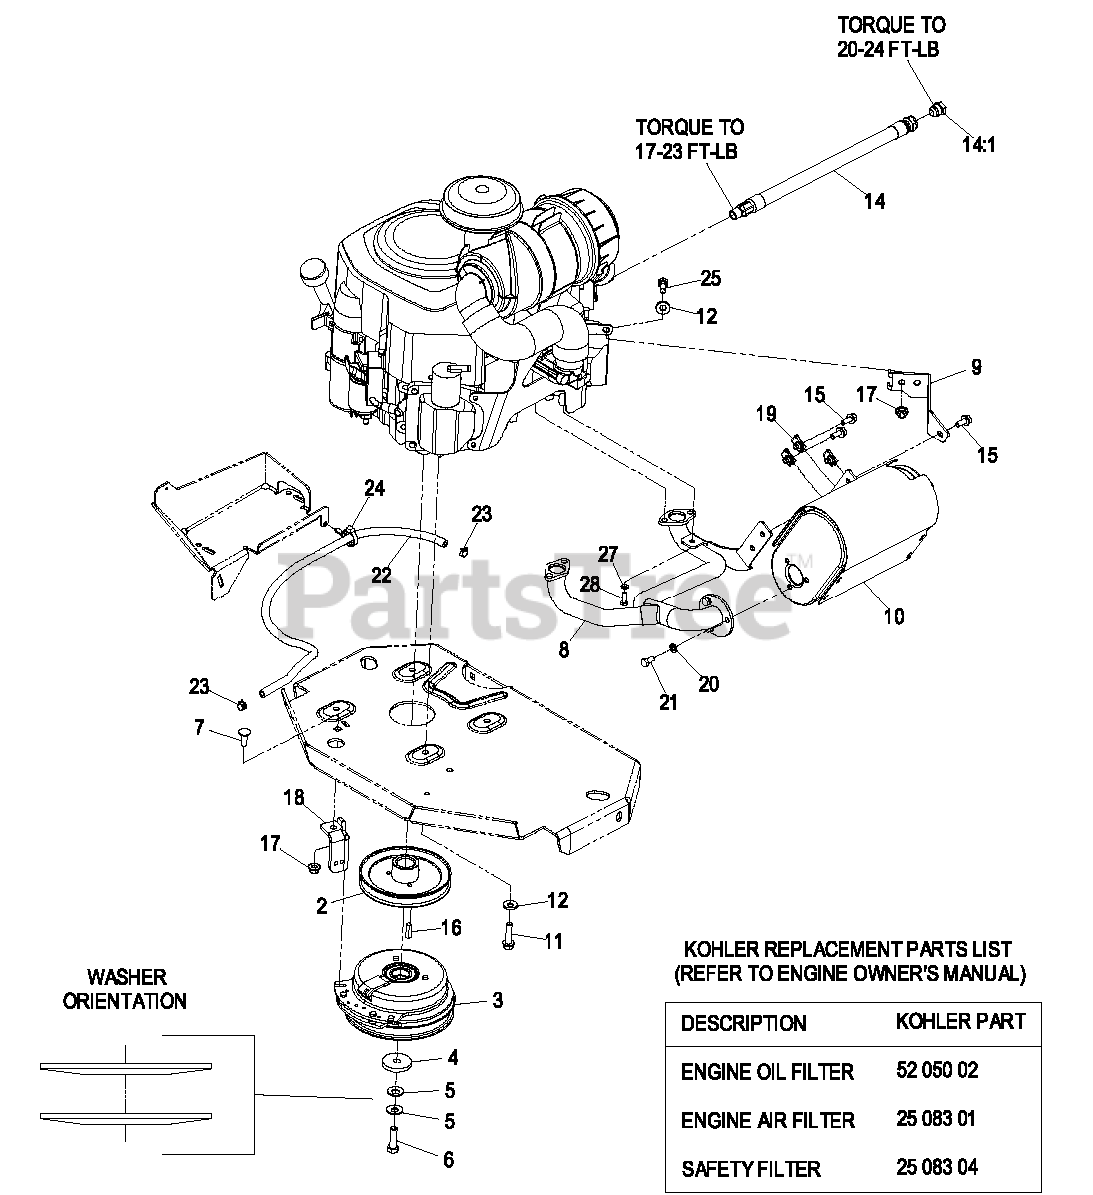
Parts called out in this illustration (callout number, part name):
2	SHEAVE
4	WASHER-CLUTCH
5	WASHER-SPRING
6	SCREW-HH 7/16-20 X 1 1/2 W/LOCTITE
7	SCREW-CARR
10	MUFFLER-ENGINE
11	SCREW-HWH
12	WASHER-BELLEVILLE
15	SCREW-HHF
17	NUT-HF, NI
18	ANCHOR-CLUTCH
20	WASHER-LOCK
21	SCREW-HH
22	HOSE-FUEL
23	CLAMP-HOSE
24	CLAMP-HOSE
25	SCREW-HH
27	WASHER-SPRING
28	SCREW-HH
